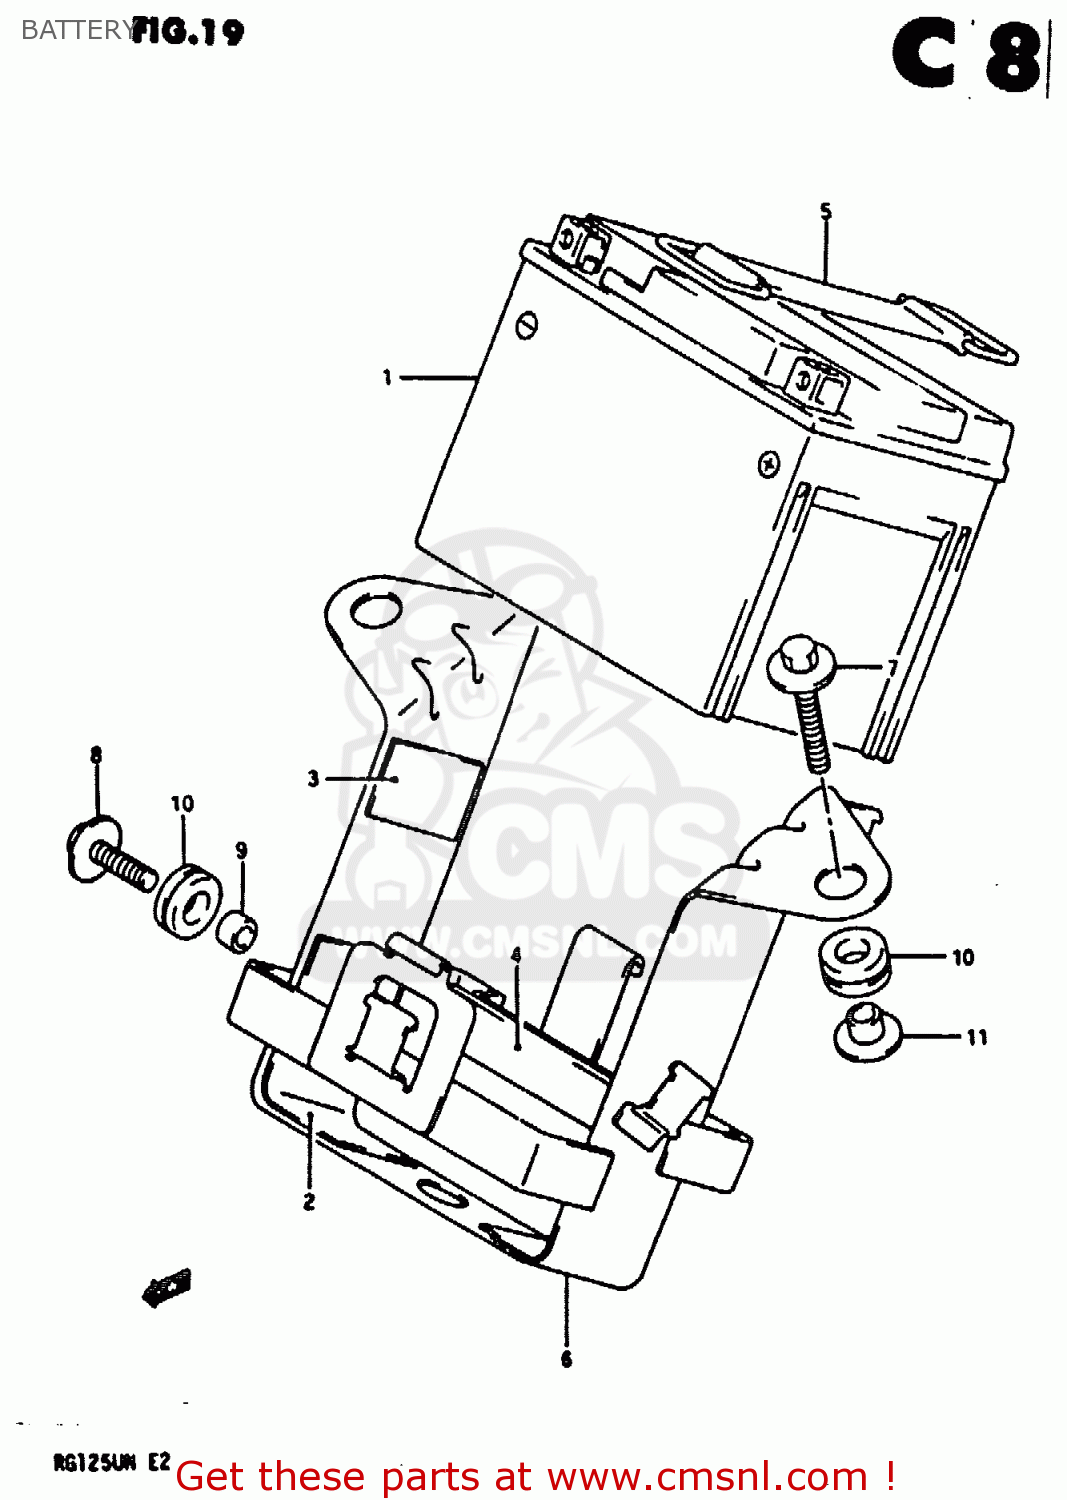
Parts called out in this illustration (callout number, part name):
1	BATTERY ASSY(YTX5L-BS,12V4.2AH
2	PROTECTOR(170X95X3.0)
3	PROTECTOR(170X95X3.0)
4	PROTECTOR,20X9
5	BAND
6	HOLDER, BATTERY
7	BOLT(6X25)
8	BOLT
9	SPACER(6.1X9X7.5)
10	CUSHION
11	PLATE,BATTERY HOLDER
